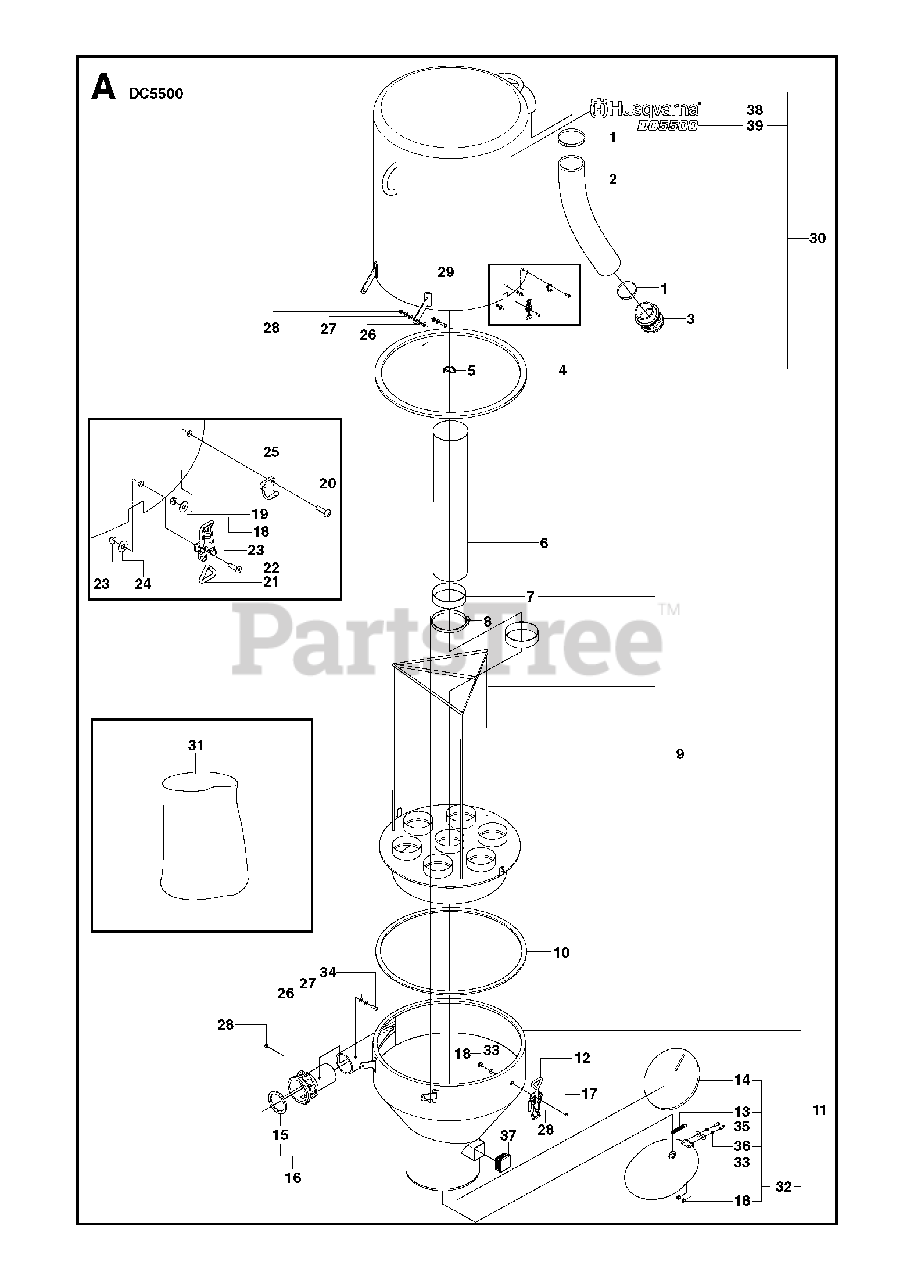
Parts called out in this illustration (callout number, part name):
17	SCREW CRCSFM
18	HEXAGON LOCKING NUT
23	HEXAGON LOCKING NUT
27	WASHER
28	HEXAGON LOCKING NUT
31	BAGSINCLUDES 200 ITEMS
